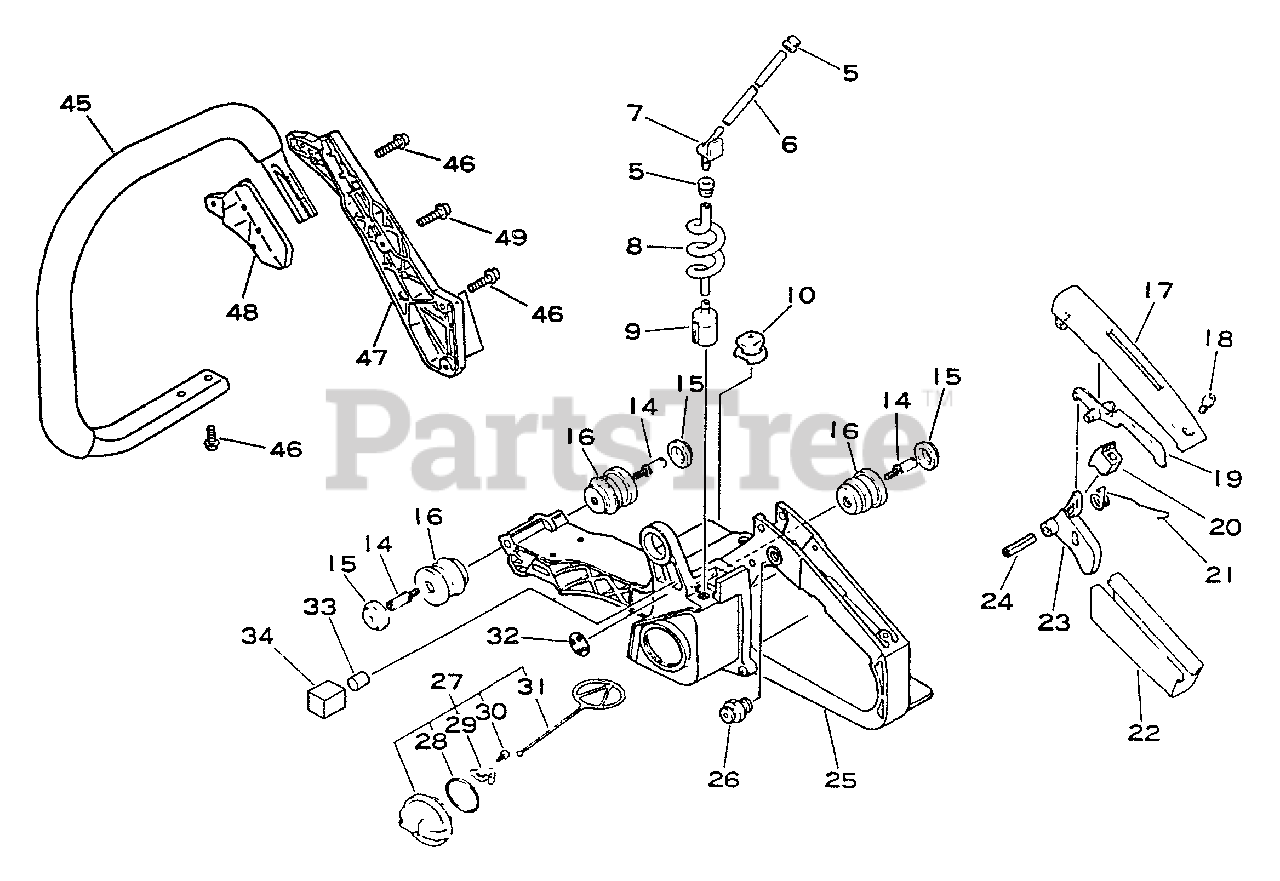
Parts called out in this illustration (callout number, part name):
5	GROMMET
6	PIPE, FUEL - 3×6×100
7	CONNECTOR, PIPE
8	PIPE - SPIRAL
9	FILTER, FUEL
15	CAP, CUSHION
16	CUSHION
17	COVER, HANDLE
18	SCREW TAPPING 4×14
19	CONTROL, THROTTLE
20	CUSHION, THROTTLE
21	SPRING, THROTTLE RETURN
23	TRIGGER, THROTTLE
24	PIN, SPRING
25	HANDLE - REAR
26	LOCK, THROTTLE
27	CAP ASSY
28	O-RING 29
29	RETAINER, CONNECTOR
30	SCREW 3×8
31	CONNECTOR, CAP L= 60 MM
32	CUSHION (B)
33	BREATHER
34	FILTER
45	HANDLE, FRONT
46	SCREW - 5×20
47	BRACKET, HANDLE - OUTER
48	BRACKET, HANDLE - INNER
49	SCREW - 5×14
